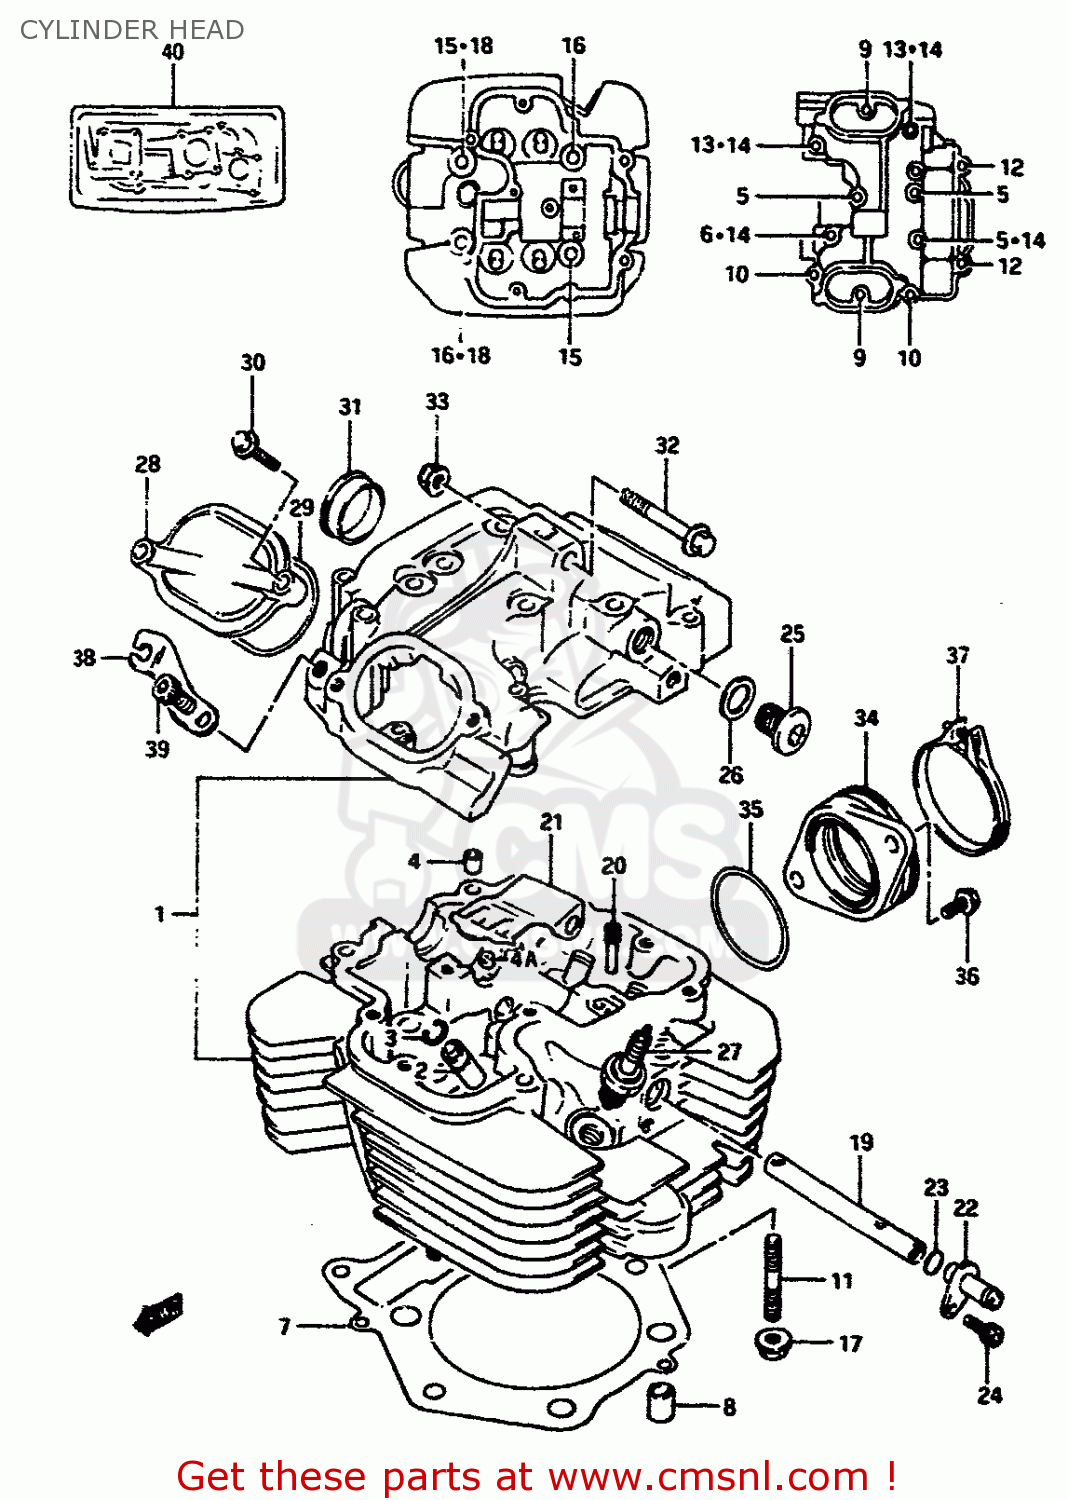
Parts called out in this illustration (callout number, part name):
1	HEAD ASSY,CYLINDER
2	GUIDE,VALVE
3	RING,SNAP
4	PIN
4A	JET,OIL GALLERY
5	BOLT ,6X60
6	BOLT 6X55
7	GASKET,CYLINDER HEAD (NAS)
8	PIN
9	BOLT 6X25
10	BOLT
11	STUD
12	BOLT(6X130)
13	BOLT ,6X60
14	GASKET (NAS)
15	BOLT(10X190)
16	BOLT(10X215)
17	NUT 8MM
18	GASKET(10.5X22X2) (NAS)
19	PIPE,CYLINDER HEAD OIL
20	SCREW (L:19.5)
21	PLATE,CYLINDER HEAD CHAMBER
22	UNION,CYLINDER HEAD OIL
23	O RING(D:1.3,ID:9.8)
24	BOLT
25	PLUG
26	GASKET(14X19.2X2) (NAS)
27	SPARK PLUG DP9EA-9
28	CAP,INSPECTION
29	O RING(D:2.4,ID:23)
30	BOLT 6X20
31	PLUG(OD:30)
32	BOLT 8X53
33	NUT
34	PIPE,INTAKE
35	O RING(D:2.4,ID:45.7)
36	PLUG ,6X20
37	CLAMP
38	LEVER,DECOMP SHAFT RH
39	BOLT
40	GASKET SET
